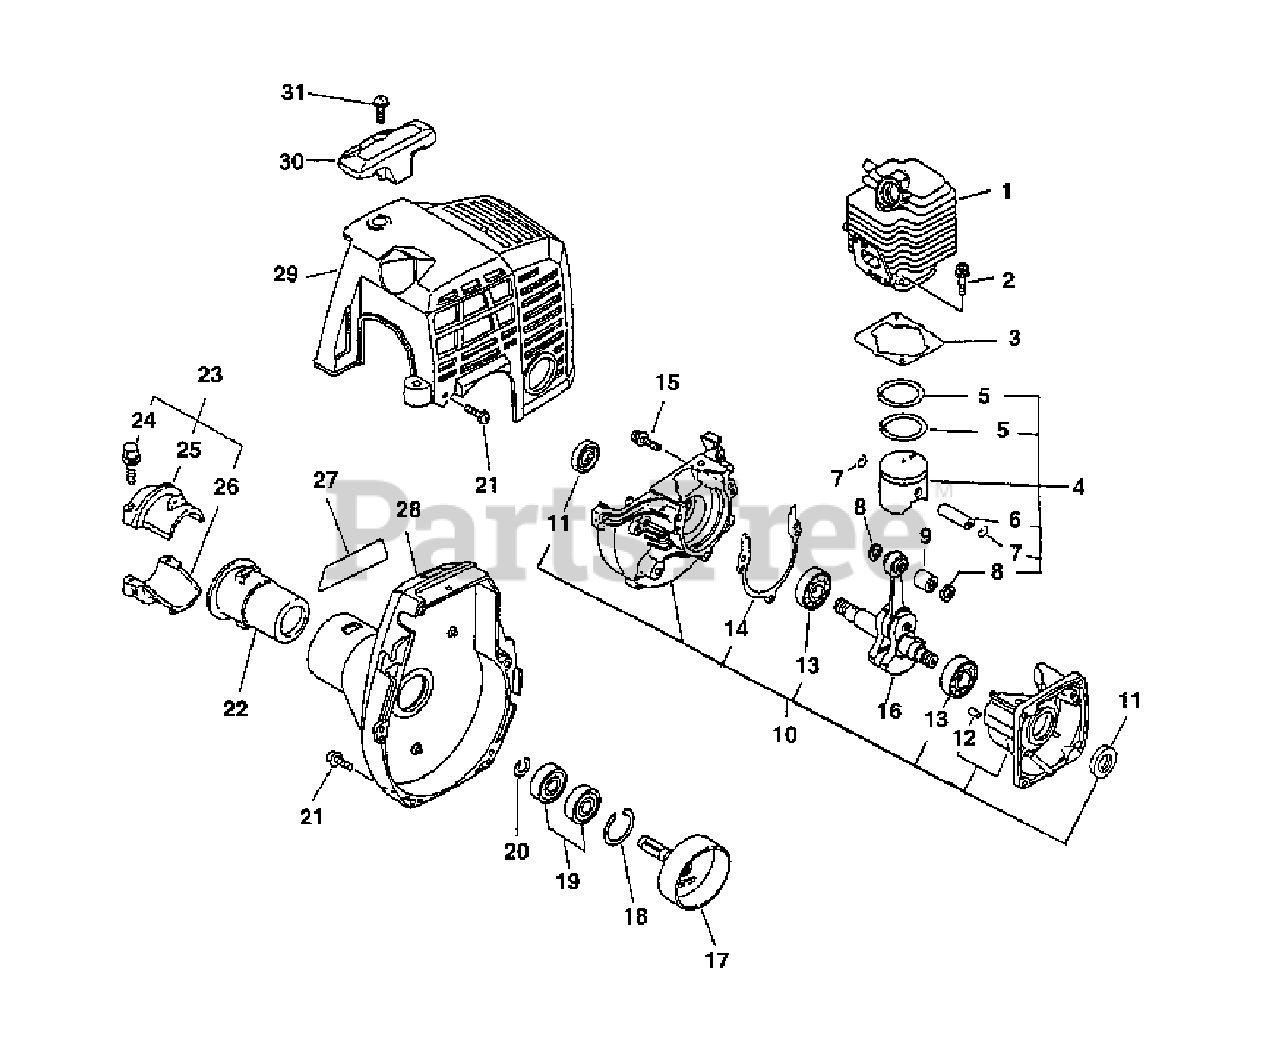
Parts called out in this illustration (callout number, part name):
1	CYLINDER
2	BOLT 5×22
3	GASKET, CYLINDER
4	PISTON KIT
5	RING, PISTON
6	PIN, PISTON 8
7	RING, SNAP
8	WASHER, THRUST
9	BEARING, NEEDLE
10	CRANKCASE KIT
11	SEAL, OIL 12
12	PIN, LOCATING 4
13	BEARING, BALL - 6201 C3
14	GASKET, CRANKCASE
15	BOLT 5×28
16	CRANKSHAFT ASSY
17	DRUM, CLUTCH
18	RING, SNAP 28
19	BEARING, BALL 6001
20	RING, RETAINING - 12
21	BOLT 4×16
22	CUSHION Ø25
23	RETAINER KIT
24	BOLT - 5×25
25	HOLDER, MAIN PIPE - UPPER
26	HOLDER - LOWER
27	LABEL, PE-2400
28	COVER ASSY, FAN
29	COVER, ENGINE
30	GUARD, TOP
31	SCREW 5×16
